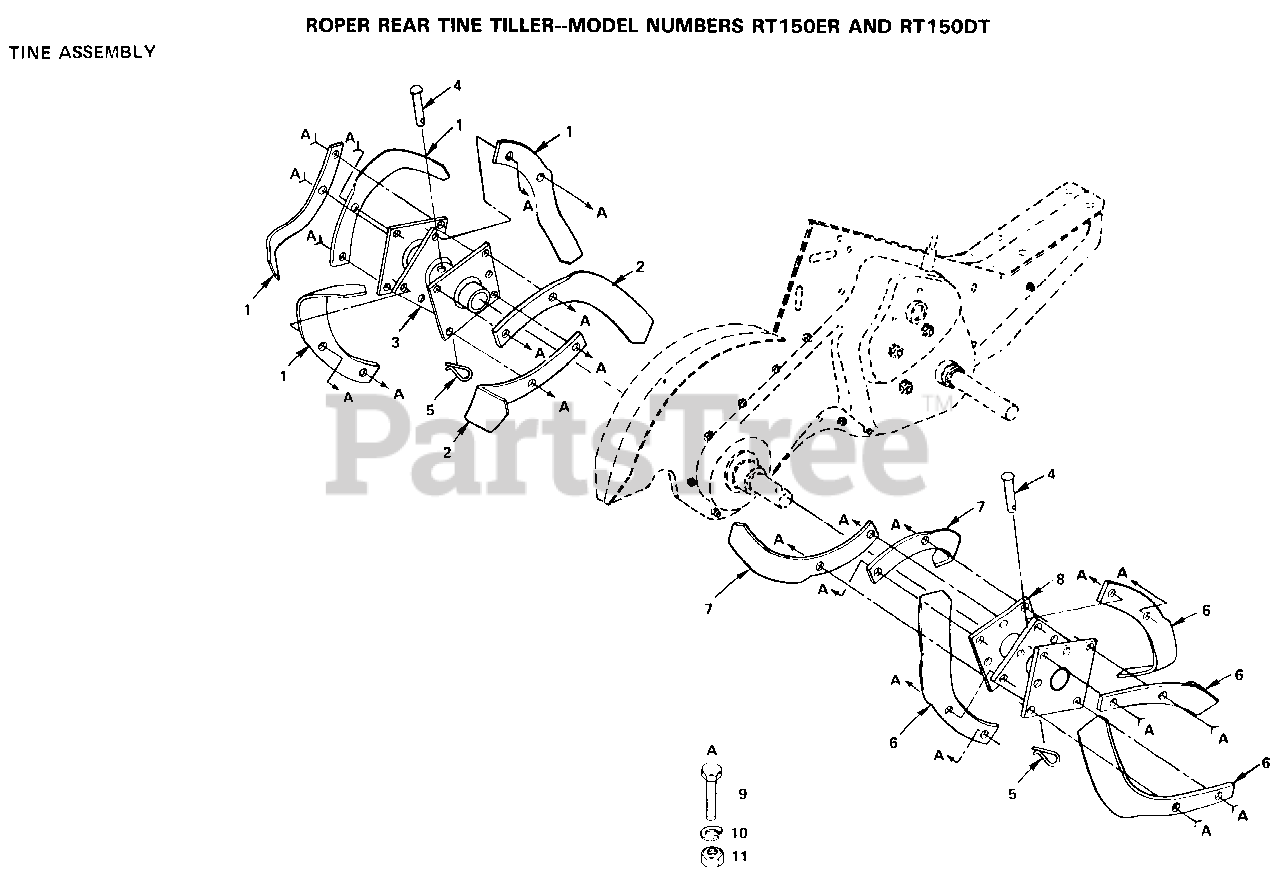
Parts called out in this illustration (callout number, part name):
2	"TINE.LH.12"""
3	TINE ASSY LH CRT
4	RIVET.PAN HD.1.75
5	RETAINER.SPRING
7	"TINE.RH.12"""
8	TINE ASSY RH CRT
9	BOLT
10	LOCKWASHER
